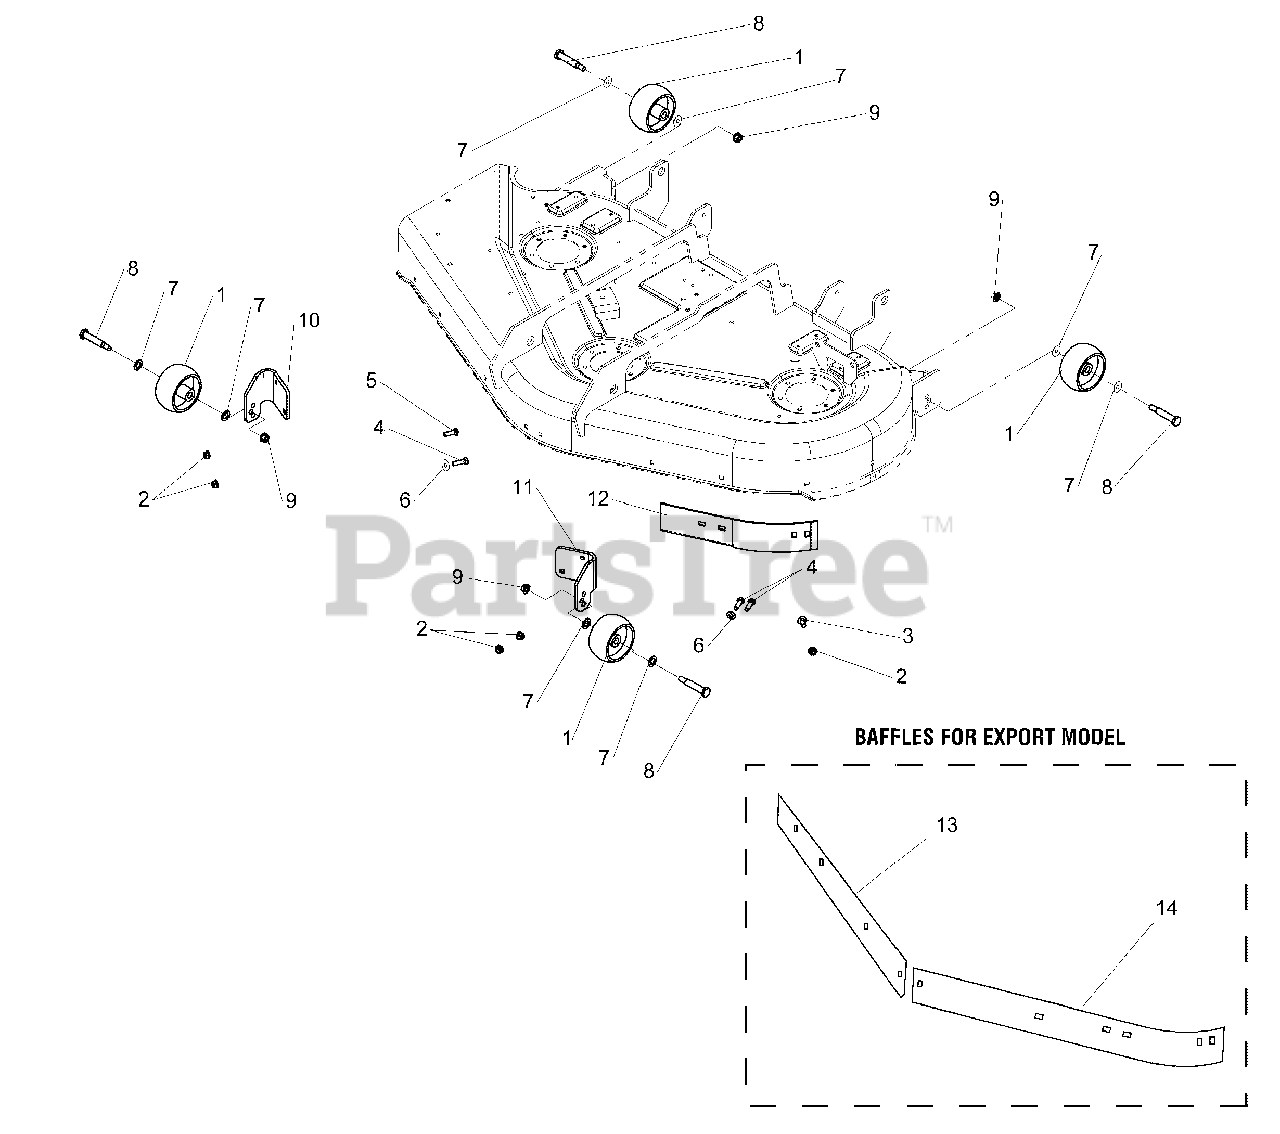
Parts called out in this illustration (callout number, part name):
1	GAUGE WHEEL
2	NUT, 5/16-18 HEX NYLOCK FLANGE
3	CARRIAGE BOLT, 5/16-18 X 3/4
4	BOLT, 5/16-18 X 1" GD5
5	CARRIAGE BOLT 5/16-18 X 3/4
6	WASHER, 5/16" SAE
7	WASHER
8	BOLT, REAR WHEEL
9	NUT, FLANGE SIDELOCK 3/8-16
10	BRACKET, GAUGE WHEEL, RH
11	BRACKET, GAUGE WHEEL, LH
12	SHORT BLOWOUT BAFFLE
13	BAFFLE-BLOWOUT RH 50" MWR - BLACK
14	BAFFLE-BLOWOUT LH 50" MWR - BLACK
15	NUT, 5/16-18 HEX NYLON LOCK
16	BOLT, 5/16-18 X 3/4", CARRIAGE
